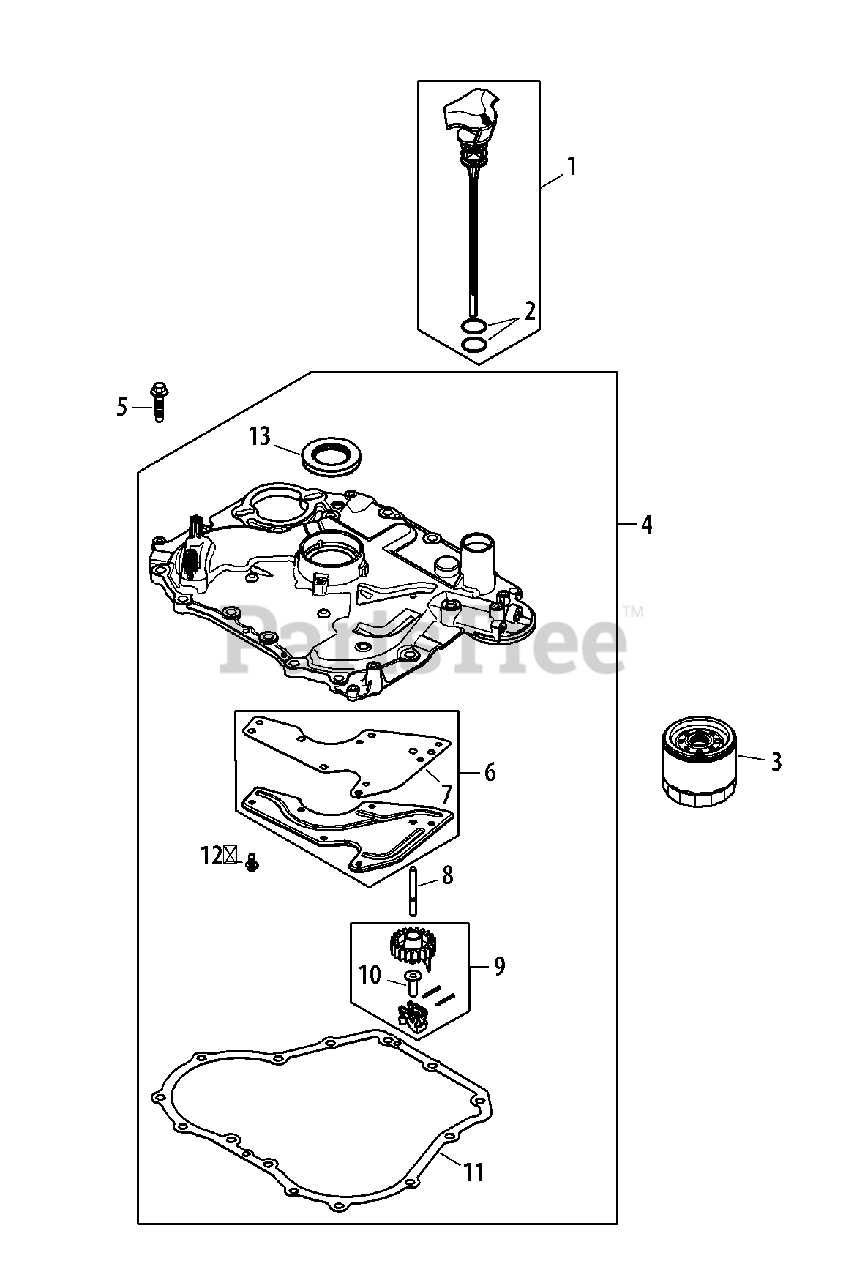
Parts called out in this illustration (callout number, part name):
1	Dipstick Ass’y-Std Yellow (Incl. 2)
4	Closure Plate Assembly (Incl. 5-14)
5	Hex Flange Screw, 1/2
6	Oil Passage Cover Kit (Incl. 7)
7	Oil Passage Gasket
8	Governor Cross Shaft
9	Governor Gear Assembly
10	Governor Regulating Pin
11	Closure Plate Gasket
12	Flg. Thd. Frm. Screw, M5 X 0.8 X 13
